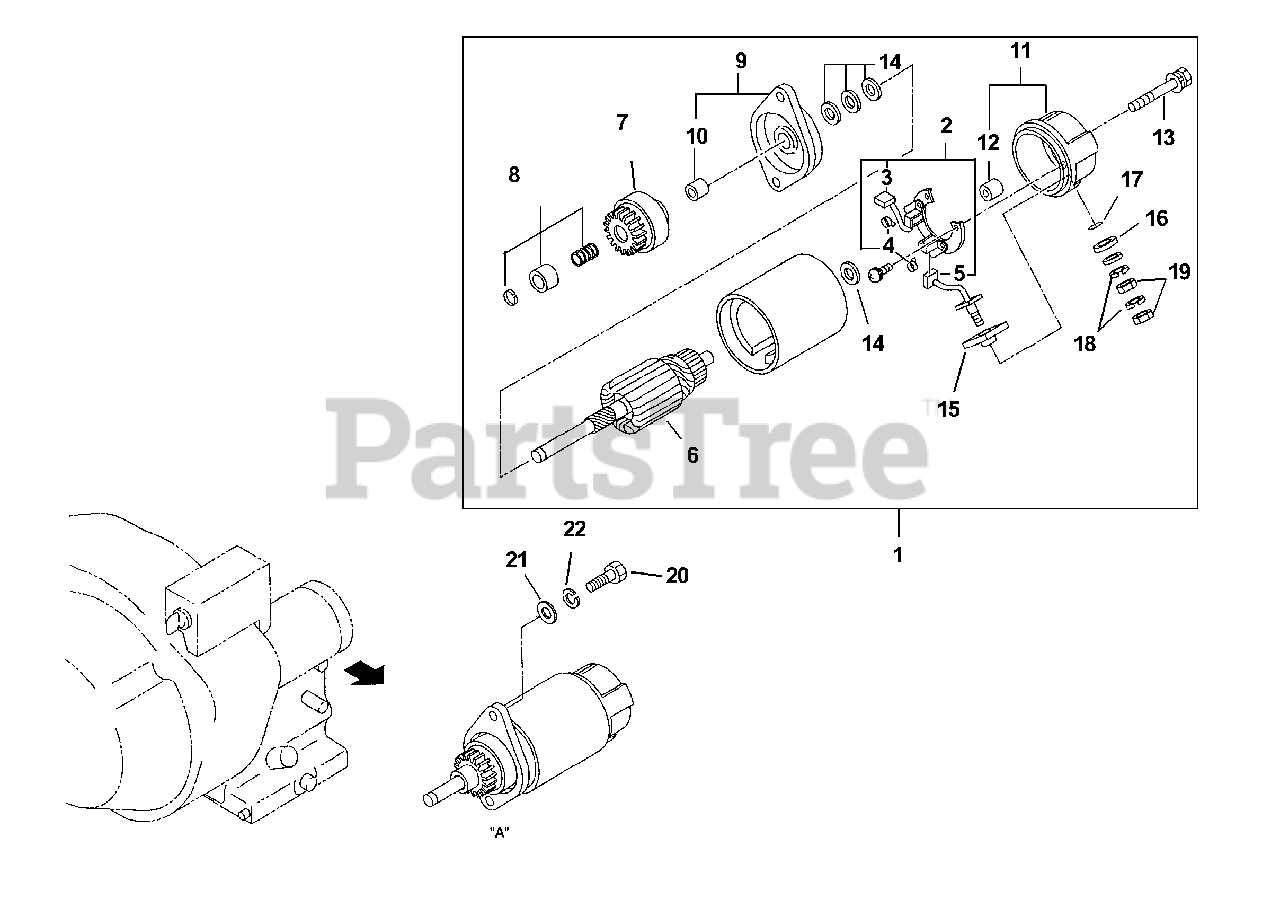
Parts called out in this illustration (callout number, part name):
1	Starting motor assy
2	Holder assy, brush
4	Spring, brush
5	Brush (-)
6	Armature assy
7	Pinion assy
8	Pinion stopper set
9	Front cover assy
10	Front metal
11	Rear cover assy
12	Case metal
13	Through bolt
14	Washer kit
15	M brush 1
16	M brush 2
18	Spring Washer
20	Bolt, starter
22	Spring washer
